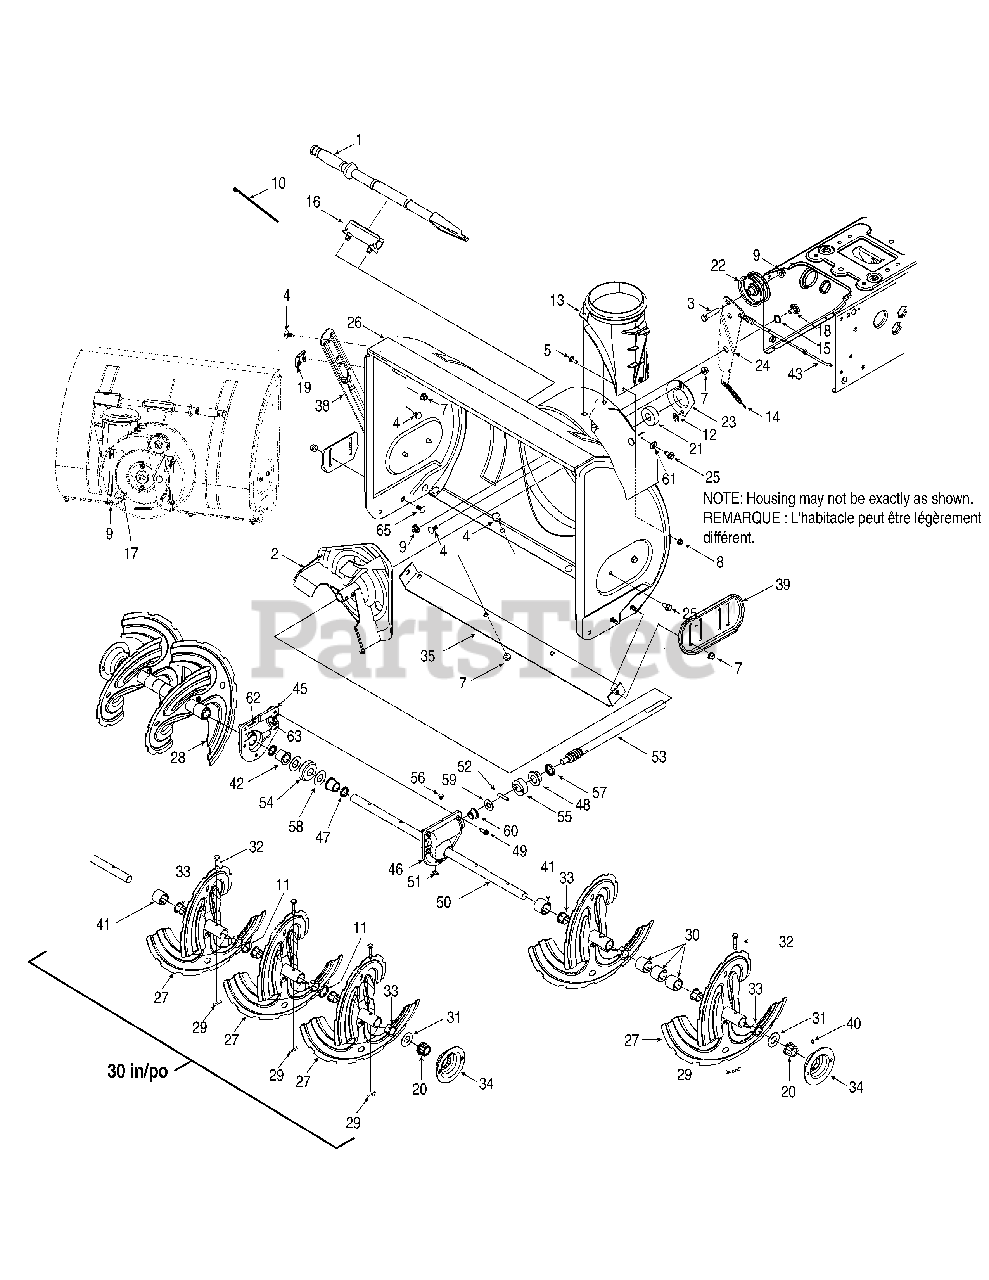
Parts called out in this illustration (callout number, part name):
1	Clean-Out Tool
2	Impeller Ass'y 12 po
3	Hex Screw 3/8-16 x 1.75
4	Carriage Bolt 5/16-18 x .75
5	Carriage Screw 1/4-20 x .75 Gr. 5
7	Flange Locknut 5/16-18 Gr. F Nylon
8	Hex L-Flanged Nut 1/4-20 Gr. F Nylon
9	Hex L-Flanged Nut 3/8-16 Gr. F Nylon
11	Spacer 1.25 x .75 x 3/16" Lg.
12	Push-on Nut .25 dia.
13	Chute Adapter (w/one pc chute crank)
14	Extension Spring .38 OD x 4.59" Lg.
15	Wave Washer .660 ID x .88 OD x .010
16	Cleanout Tool Mount
17	Shld. Scr. .500 Dia. x .335" Lg.
18	Shoulder Scr .625 Dia x .170
20	Hex. Flange Brg. .751" I.D.
21	Self-aligning Bearing
22	Flat Idler Pulley 2.75" OD
23	Bearing Housing 1.85 ID
24	Auger Idler Brake Bracket
25	Hex TT Screw 3/8-16 x .75
26	Auger Housing - 24" Models
26	Auger Housing - 26" Models
26	Auger Housing - 28" Models
26	Auger Housing - 30" Models
27	Spiral Ass'y LH
28	Spiral Ass'y RH
29	Bow Tie Cotter Pin
30	Spacer 1.25 x .75 x 1.00 - 24-28" Models
30	Spacer 1.25 x .75 x 2.00 - 30" Models
31	Flat Washer .760 ID x 1.49 OD
32	Shear Pin .25 x 1.5 Gr. 2
33	Flange Bushing
38	Drift Cutter -
39	Reversible Slide Shoe (steel)
40	Grease Fitting
41	Spacer 1.25 x .75 x 1.00
42	Flange Bearing.75 ID x 1.0 OD x .975
43	Auger Clutch Cable
45	RH Reduced Auger Housing
46	LH Reduced Auger Housing
47	Oil Seal .75 x 1.0 x .125
48	Flange Bearing .75 ID x 1.00 OD x .50
49	Thd Forming Scr. 1/4-20 x .75
50	Auger Axle 24" Models
50	Auger Axle 26" Models
50	Auger Axle 28" Models
50	Auger Axle 30" Models
51	Hi Pro Key 3/16 x 5/8
52	Dowel Pin .25 OD x 1.2
53	Worm Shaft .75 OD
54	Worm Gear 24"-26" Models
54	Worm Gear 28"-30" Models
55	Thrust Collar
56	Plug, 1/4 x .437
57	Oil Seal .75 x 1 x .131
58	Flat Washer .76 ID x 1.5 OD x .03
59	Fl. Washer .510 x 1.120 x .060
60	Flange Bearing .75 ID x 1.0 OD x .925
61	Cupped Washer .345 ID x .88 OD x .060
63	Grease - Alvania EP Lead Free
65	Carriage Bolt 5/16-18 x .75 (w/steel slide shoes)
67	Flat Washer .349 ID x .879 OD x .063
